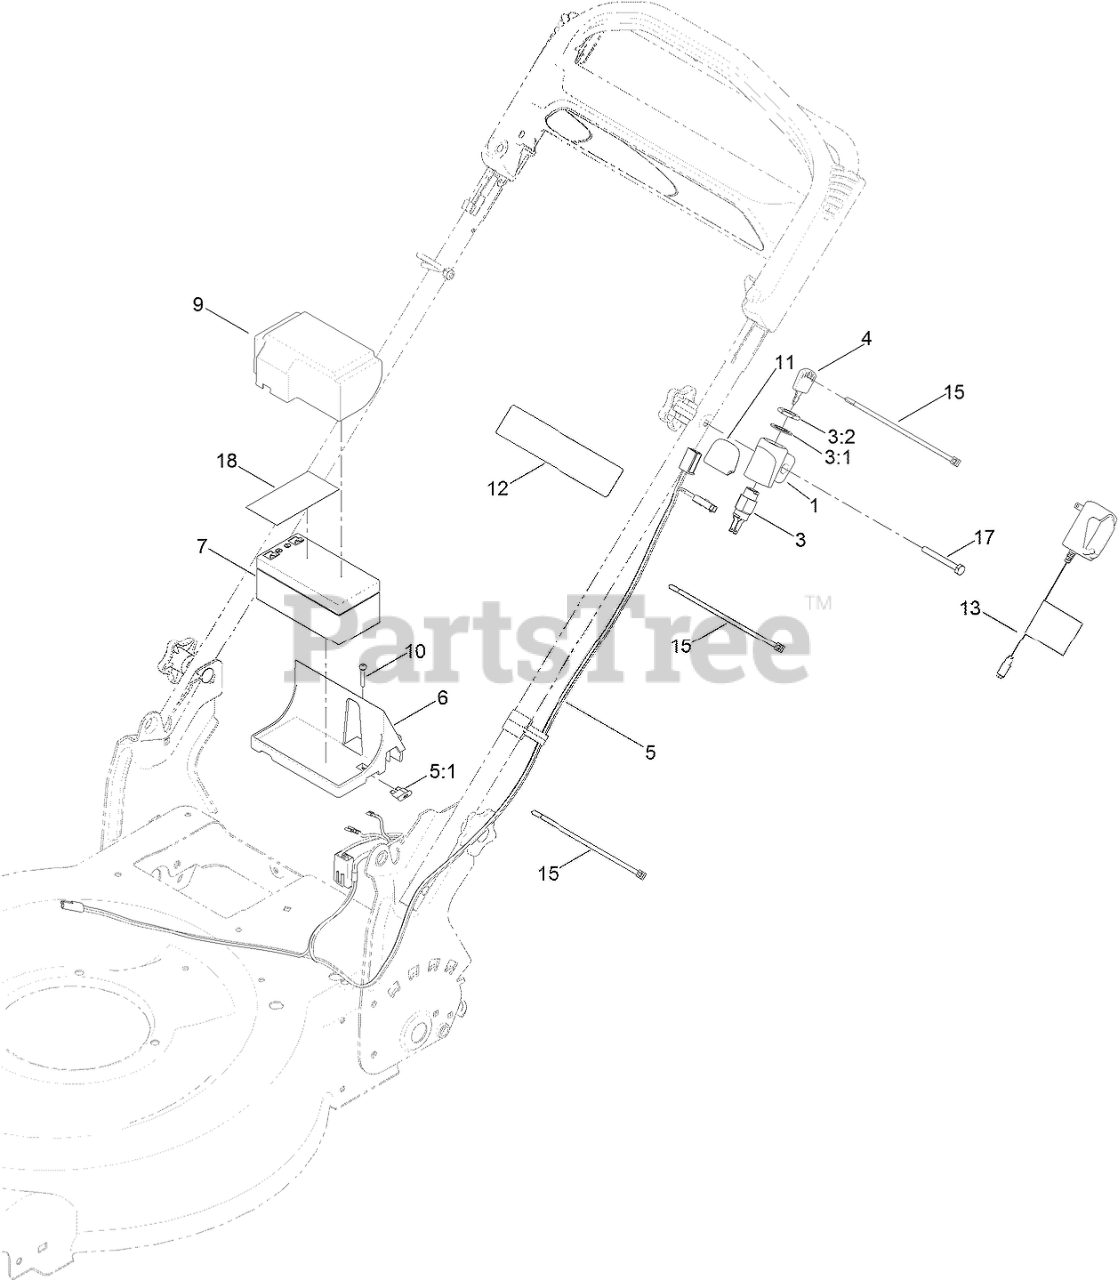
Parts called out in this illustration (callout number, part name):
1	MOUNT-SWITCH
3	STARTER SWITCH ASM
3:1	WASHER-TOOTH, INTERNAL
3:2	NUT-HH
5	HARNESS-WIRE, ES
5:1	FUSE-40 AMP
6	TRAY-BATTERY
7	BATTERY-WET
9	COVER-BATTERY
10	SCREW-PPH, PLASTITE
11	DECAL-ELECTRIC START
12	DECAL-WARNING
13	CHARGER-CE
15	TIE-CABLE
17	SCREW-HH
18	DECAL-TERMINAL, BATTERY
